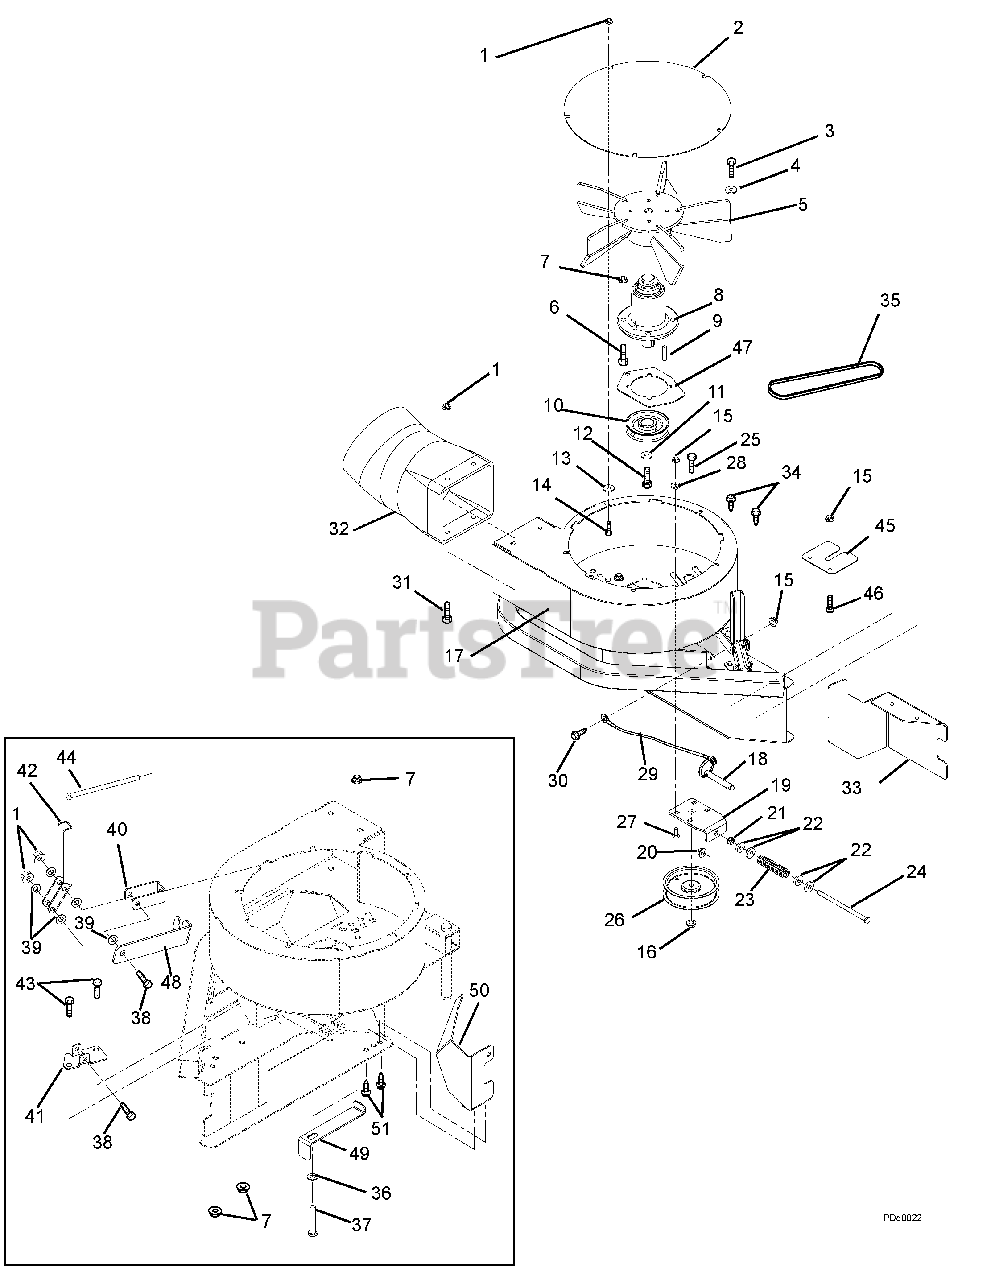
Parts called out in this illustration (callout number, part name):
1	Nut, .31-18 Nyloc Flange
2	Cover, Blower
3	Bolt, Hex .62-18 x 1.75
4	Washer, Bevelled .63 x 1.625 x .14
5	Weldment, Impeller
6	Bolt, Hex .38-16 x 1.25 Grade 5
7	Nut, .38-16 Nyloc Flange
8	Maintenance Free Spindle Assembly
9	Key, Square .25 x .25 x 1.00 RC 40-50
10	Weldment, Pulley-V 3.50 x 1.004 with Key
11	Washer, Flat Steel .39 x 1.5 x .125
12	Bolt, Hex .38-16 x 1.00 EP30
13	Nut, Push .312
14	Bolt, Round Head Square Short Neck .31-18 x .75 Grade
15	Nut, Locking-Top-Flange .25-20
16	Nut, .38-16 Nyloc Flange
17	Weldment, Blower Housing
18	Pin, Spring Ball .375OD x 1.50
19	Bracket, Adjustable Idler
20	Nut, .31-18 Nyloc Flange
21	Nut, Spin Lock-Flange .312-18
22	Washer, Flat Steel .38 x .87 x .179
23	Spring, Compression .092 x .77 x 3.13
24	Bolt, Hex .31-18 x 5.50 Grade 5
25	Bolt, Hex .38-16 x 1.75 Grade 5
26	Pulley, Idler 4.00
27	Bolt, Round Head Square Neck .25-20 x .75 Grade 5
28	Bushing, Flange .265 x .437 x .250 x .750
29	Cable, Hood
30	Bolt, Hex .25-20 x .75 Grade 5
31	Bolt, Hex .31-18 x .75 Grade 5
32	Adapter, Hose
33	Baffle, Blower 44/48"
34	Screw, Tapping .38-16 x .50 Hex Washer Head
35	V-Belt, 44" and 48" Mower Deck
36	Washer, Flat, STL .406 x .812 x .065
37	Bolt, Hex .38-16 x 1.00 Grade 5
38	Bolt, Hex .31-18 x 2.00 Grade 5
39	Washer, Flat - Nylon .375 x .75 x .060
40	Link, Idler Release
41	Mount, Idler Release Lever
42	Lever, Idler Release
43	Bolt, Hex .38-16 x .75 Grade 5
44	Bolt, Hex .31-18 x 5.50 Grade 5
45	Finger Guard 44-, 48-, and 52-Inch Deck
46	Bolt, Hex .25-20 x .50 Grade 5
47	Plate, Bearing Housing Support
48	Lock, Idler Release Lever
49	Finger - Belt
